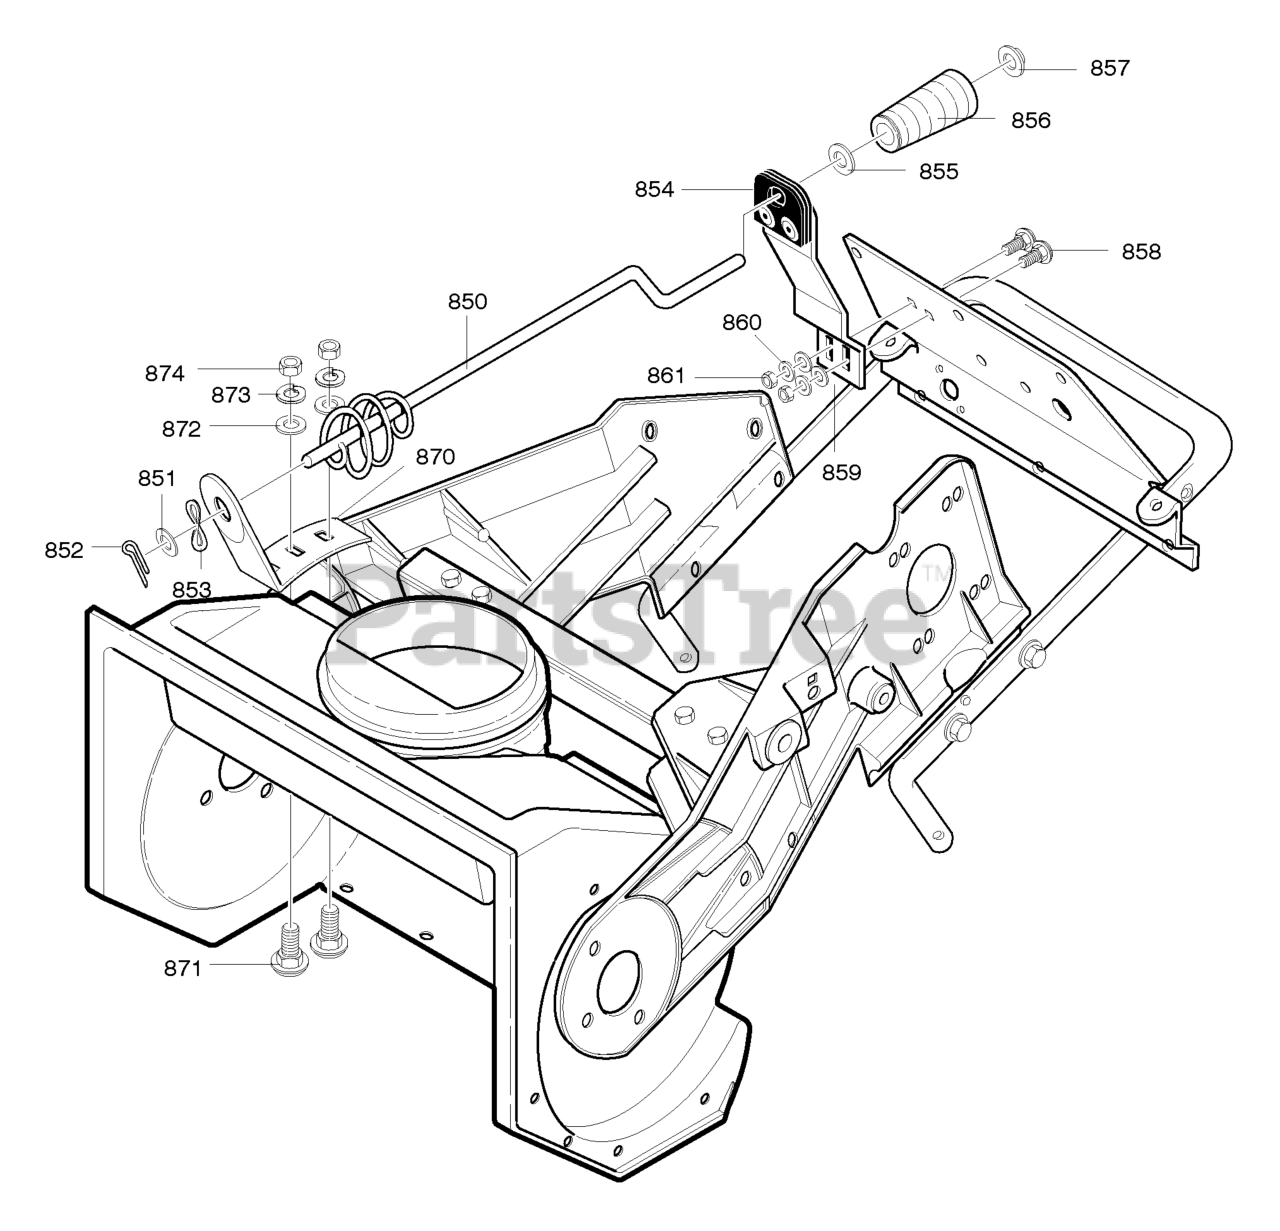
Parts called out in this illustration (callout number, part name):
850	ROD, CHUTE
851	WASHER, FLAT .406X.81X.066
852	PIN, COTTER
853	WASHER CURVED
854	ASSY, CHUTE CRANK
855	WASHER, FLAT .406X.81X.066
856	KNOB, SLEEVE
857	NUT, PUSH
858	BOLT, 1/4-20X.63 CARR.
859	WASHER, FLAT .344X.69X.065
860	WASHER, .31X.58X.08
861	NUT, 1/4-20 REGHEX
870	BRKT, CHUTE ROTATE
871	BOLT, 5/16-18X.75 CARR
872	WASHER, FLAT .349X.69X.066
873	WASHER, SPTLK .31X.58X.08
874	NUT, 5/16-18 REGHEX
